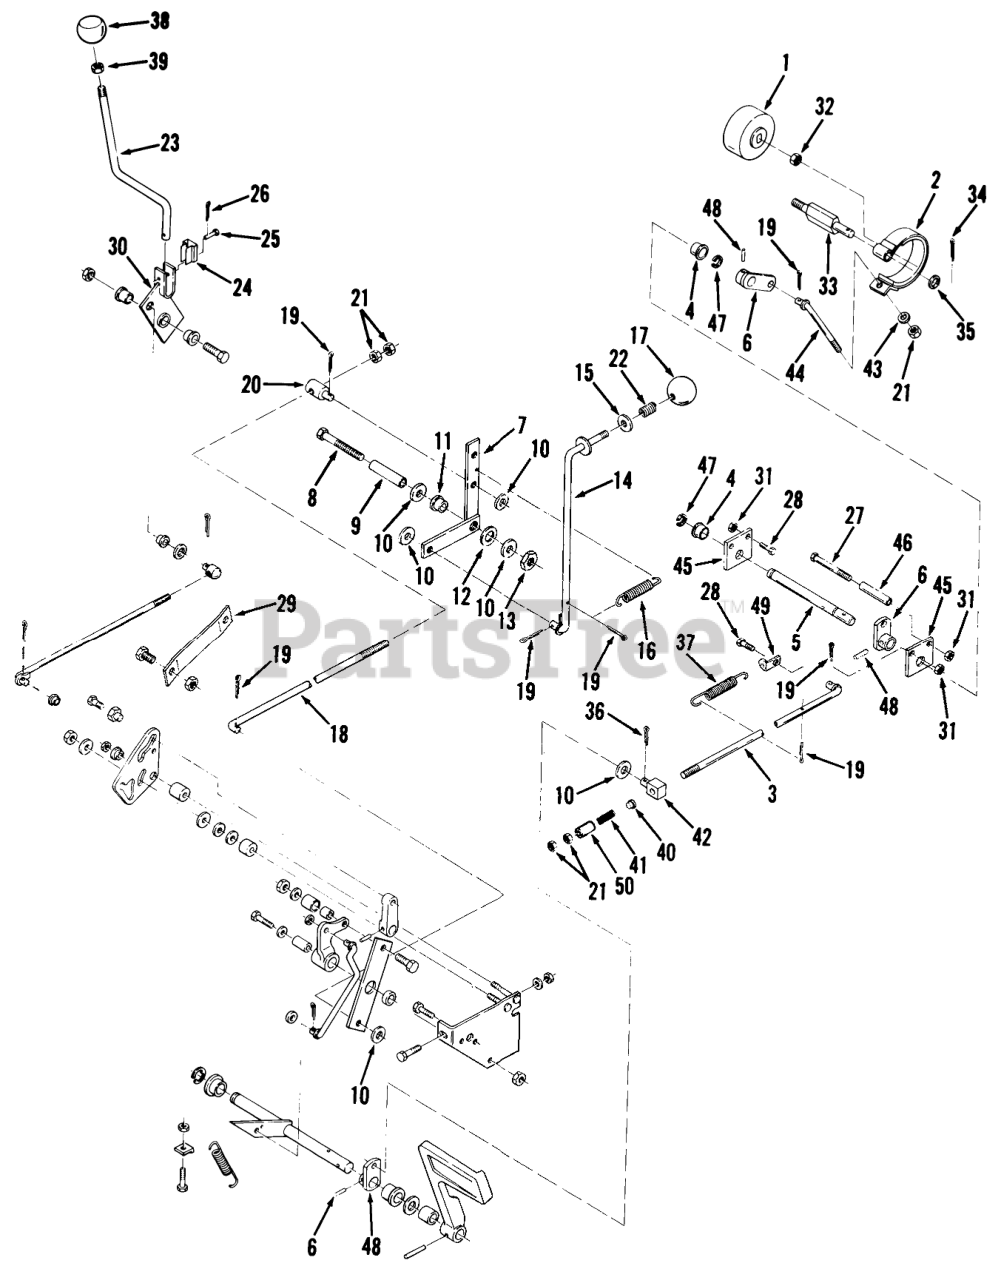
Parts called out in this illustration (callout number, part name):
1	ASSY-BRAKE DRUM
2	ASSY-BRAKE BAND&LINE
3	Assy-Rod
4	BEARING
5	Brake Shaft
6	Brake Arm
7	Assy-Arm Brake
8	HHCS
9	Spacer
10	Washer
11	FLANGED BUSHING
12	Washer
13	NUT
14	Assy-Brake Rod
15	Washer-Nylon
16	SPRING
17	SHIFT KNOB
18	Rod
19	Cotter Pin
20	TRUNNION-LIFT
21	Nut
22	SPRING-COMPRESSION
23	HANDLE
24	Spring
25	Clevis Pin
26	Cotter Pin
27	Bolt
28	BOLT
29	Brace
30	Assy-Pivot
31	Nut
32	E.S. Nut 9/16-18 Thin
33	DISC WHEN EXP
35	Washer
36	Pop Rivet
37	SPRING
39	Jam Nut
40	BUSHING-FLANGED
41	SPRING
42	Trunnion
43	SPACER
44	ROD CLAMP
45	Support Plate
46	SPACER .375 ID X 1.6
47	E-RING
48	ROLL PIN 1/4X1 1/8
49	CLIP - SPRING
